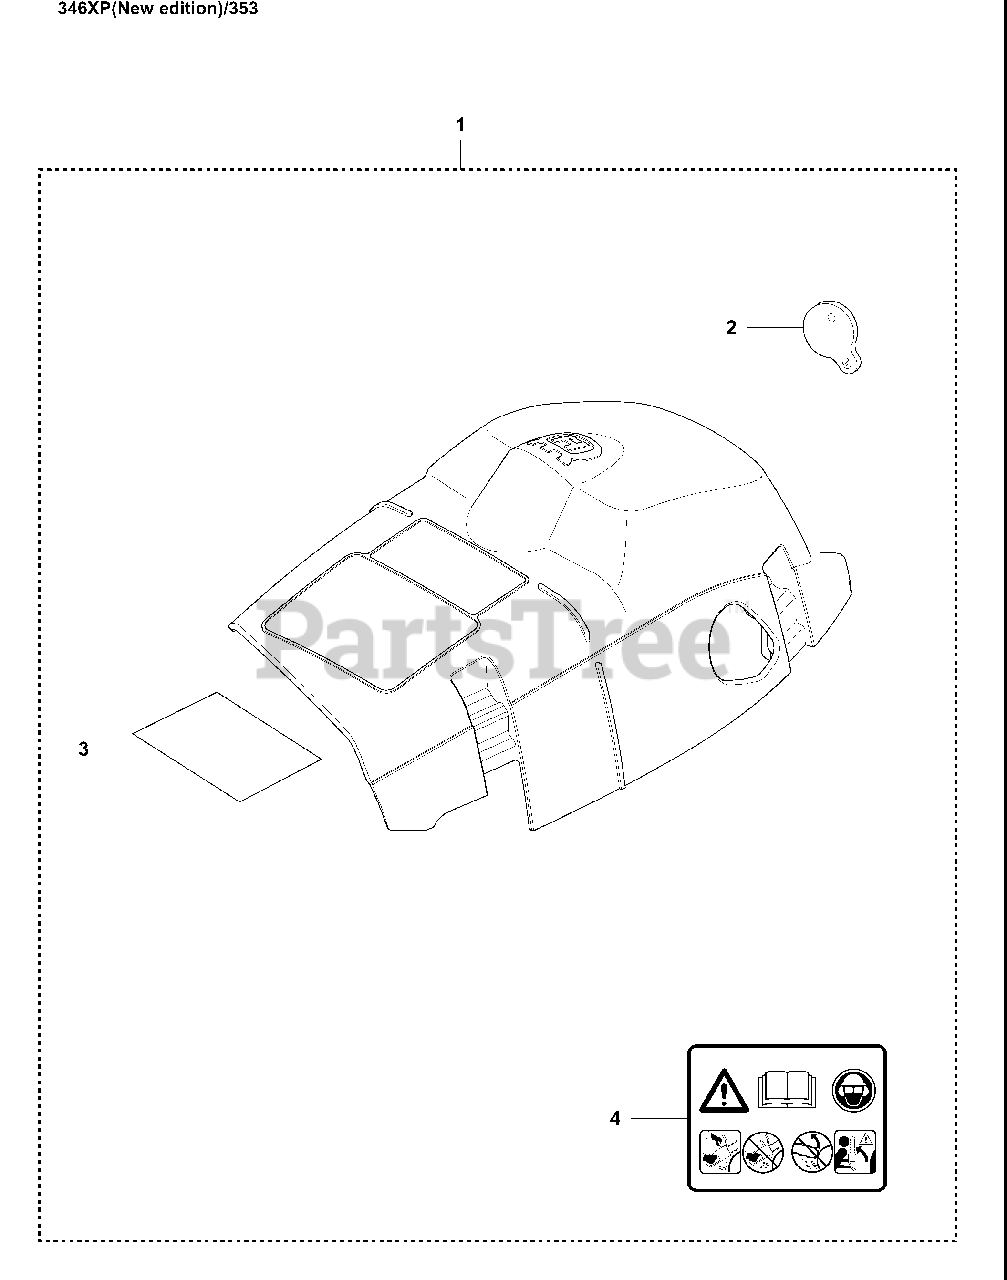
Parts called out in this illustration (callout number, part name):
1	CYLINDER COVER ASSY
2	COVER
3	INSULATING FOIL/CYLINDER COVER
